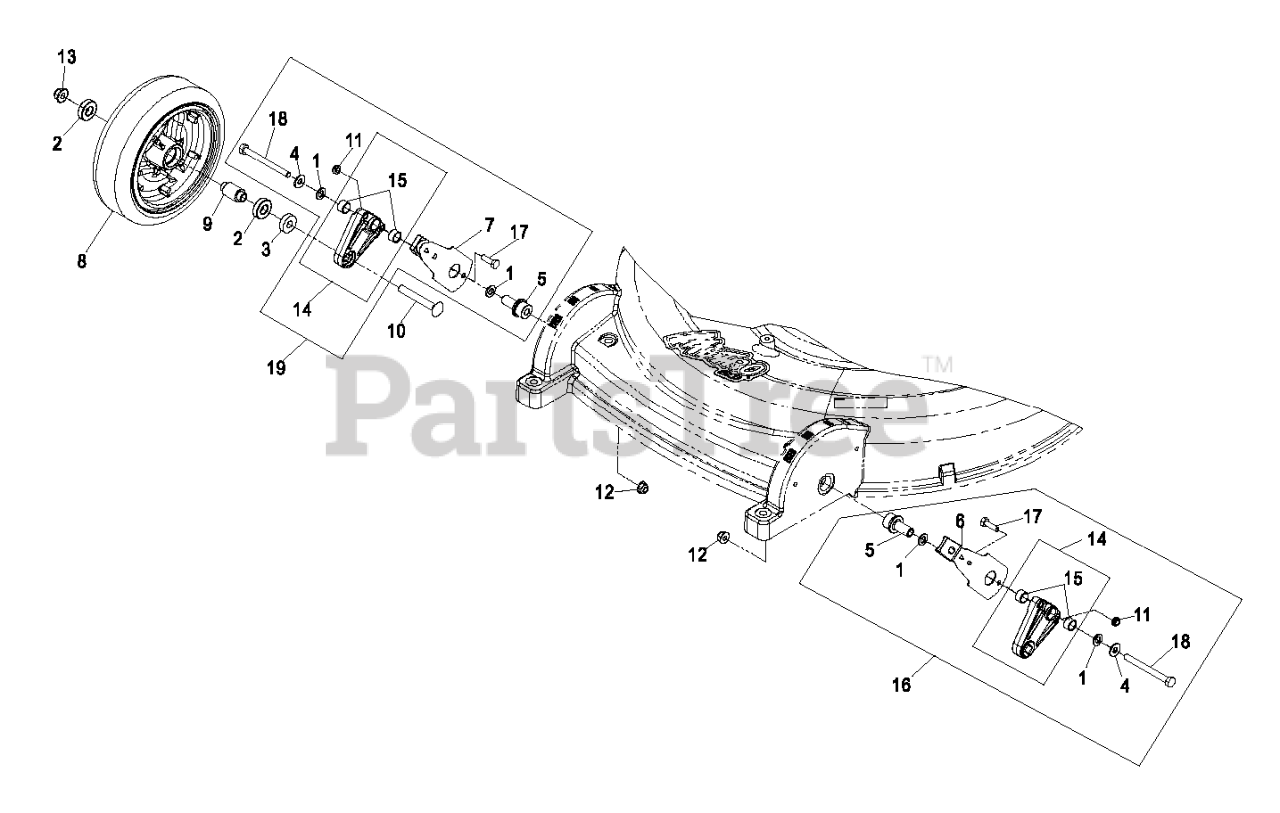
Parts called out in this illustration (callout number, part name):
1	WASHER-THRUST, NYLON
2	BEARING-WHEEL
4	WASHER-FLAT
5	BUSHING-PIVOT, WHEEL
6	KIT,SPRING ARM FRONT LH
6	KNOB-ARM
7	KIT,SPRING ARM FRONT RH
7	KNOB-ARM
8	ASM,8" WHEEL AND TIRE
9	SPACER-WHEEL, FRONT
10	SCREW-CARR
11	NUT-LOCK, NI
12	NUT-HF, NI
13	NUT-HF, NI
15	BEARING,SLEEVE
17	SCREW-HH
18	SCREW-HH
